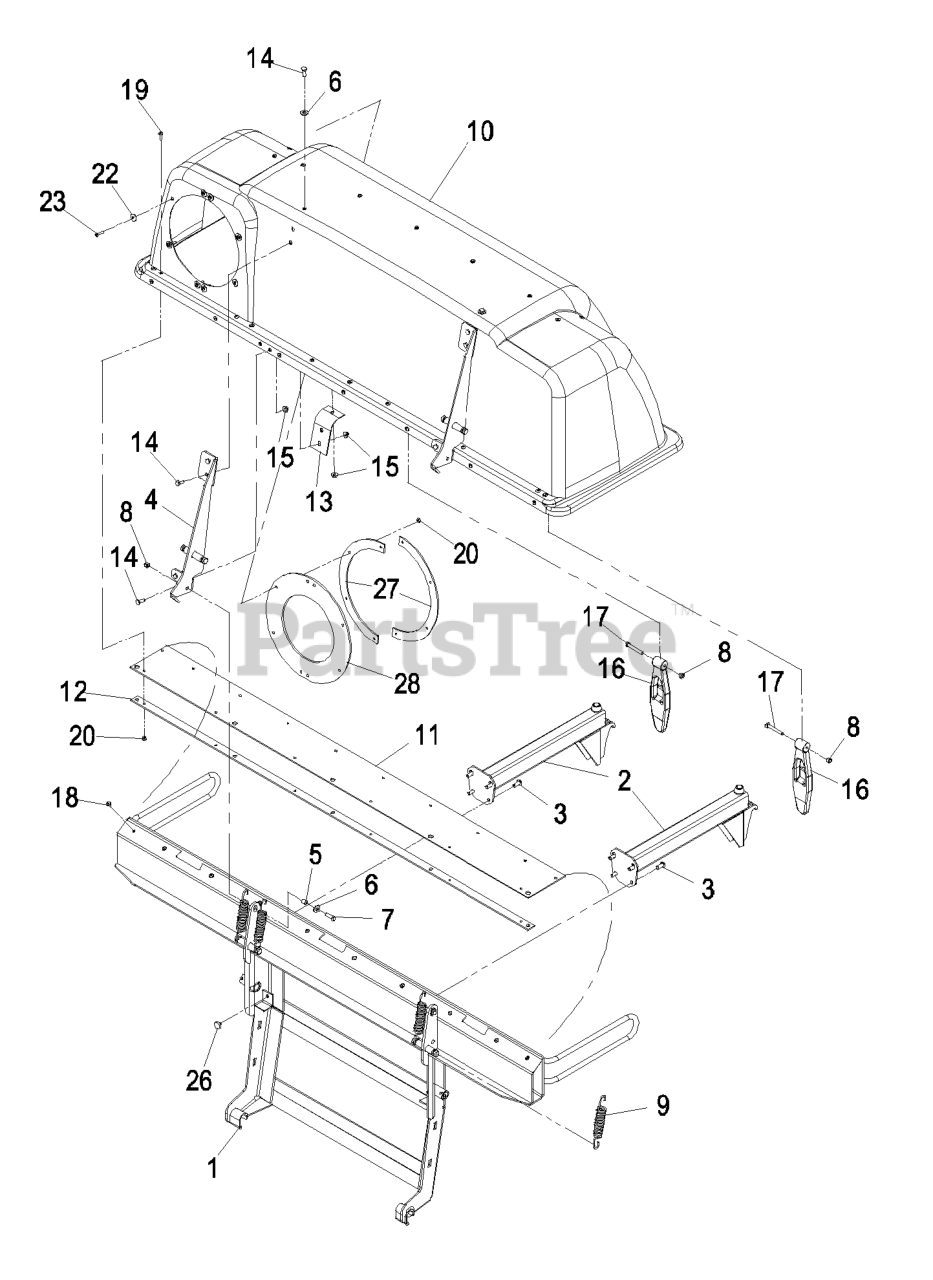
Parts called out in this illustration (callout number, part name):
1	FRAME-TRIPLE BAGGER
2	BAG SUPPORT ASM
3	SCREW-HSBH
6	WASHER-FLAT
7	SCREW-HH
8	NUT-LOCK, NI
9	SPRING-EXTENSION
10	ASM, HOOD
11	SEAL-HINGE
12	PLATE-BACKING
13	REINFORCEMENT-HOOD, BAGGE
14	SCREW-HH
17	SCREW-HH
18	RIVET-BLIND
19	SCREW-HEAD, TRUSS
20	NUT-LOCK, NI
22	WASHER-FLAT
23	SCREW-PPH
27	CLAMP-SEAL
28	SEAL-TUBE
